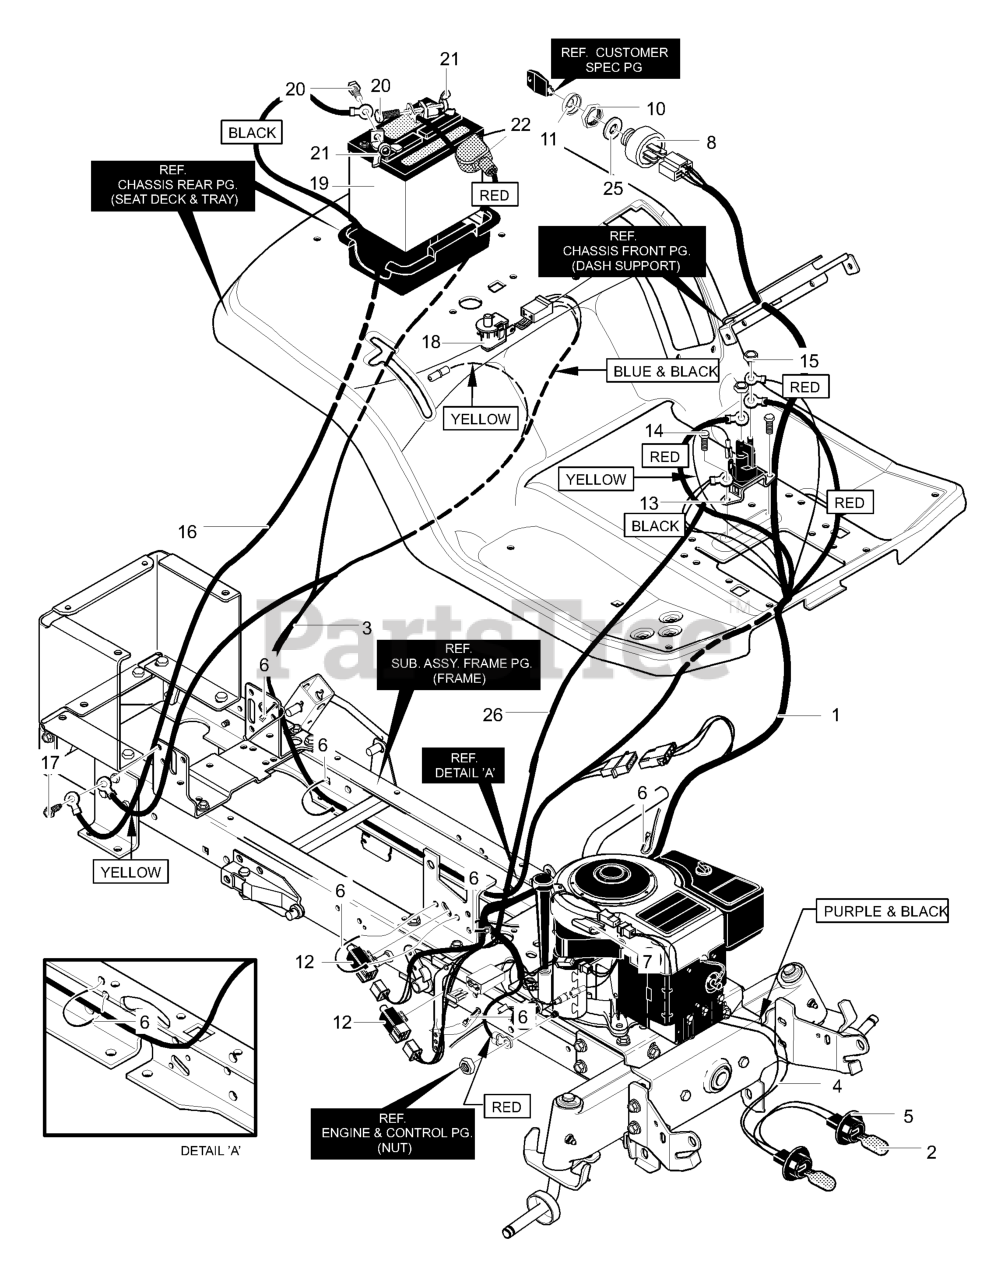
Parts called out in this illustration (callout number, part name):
1	HARNESS
2	BULB, LIGHT
3	WIRE HARNESS, REAR
4	WIRE HARNESS, HEADLIGHTS
5	SOCKET, LAMP
6	TIE, CABLE
7	WIRE CLIP, ADHESIVE
8	SWITCH, IGNITION
10	NUT
11	BOOT, SWITCH
12	SWITCH, LIMIT
13	SOLENOID
16	WIRE, GROUND
18	SWITCH, SEAT
19	BATTERY
20	BOLT
21	WINGNUT
22	BOOT, BATTERY
25	WASHER
26	WIRE, SOLENOID
